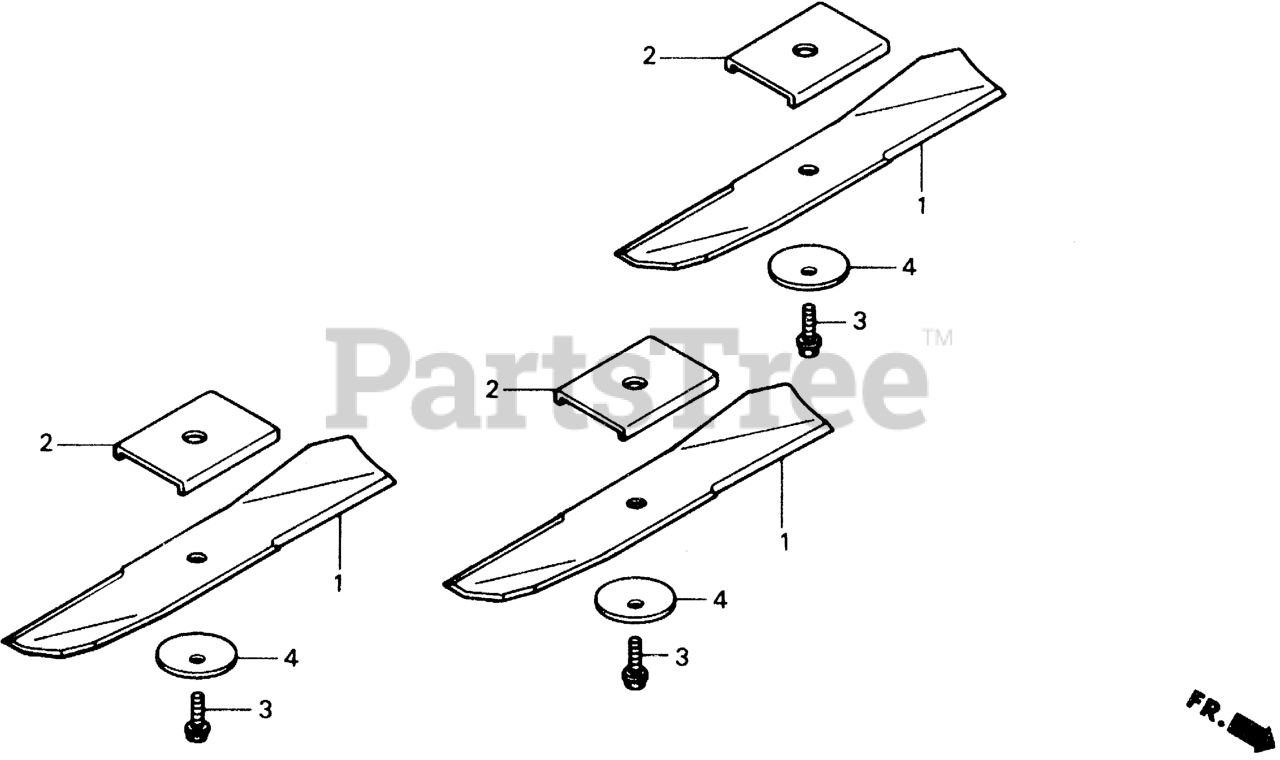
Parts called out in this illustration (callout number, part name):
1	BLADE, ROTARY
2	HOLDER, BLADE (B)
3	BOLT, BLADE HOLDER (10X28)
4	WASHER, BLADE
